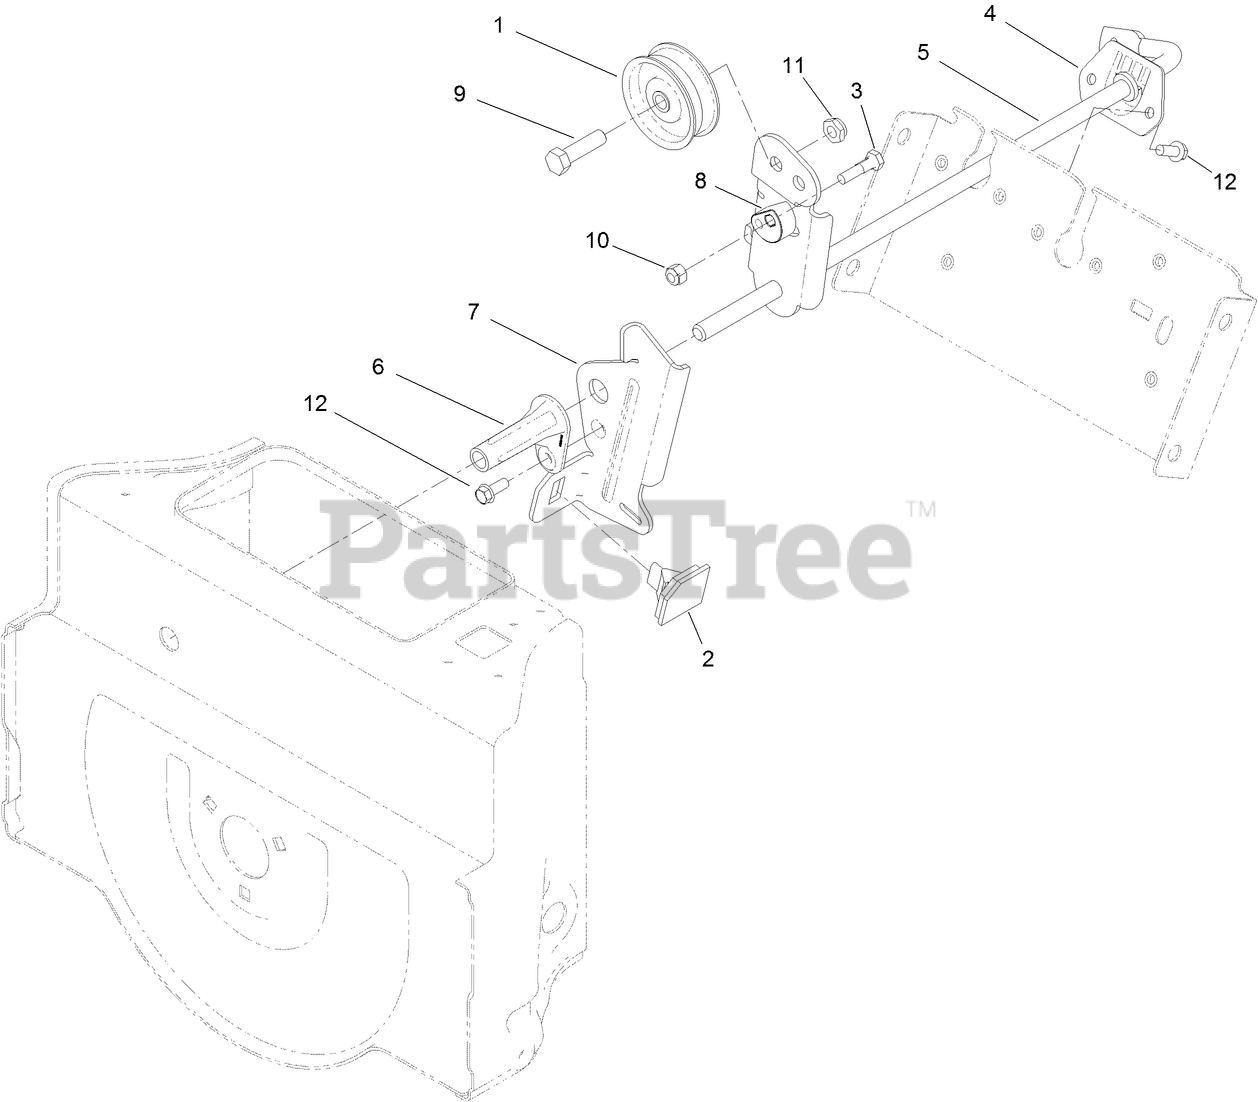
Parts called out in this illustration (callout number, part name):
1	PULLEY-IDLER
2	PAD-BRAKE
3	BOLT-PIVOT, ECCENTRIC
4	BUSHING-ROD, CLUTCH
5	IMPELLER CLUTCH ASM
6	PIVOT-BRAKE, IMPELLER
7	ARM-BRAKE, IMPELLER
8	ECCENTRIC-BRAKE, IMPELLER
9	SCREW-HH
10	NUT-LOCK, NI
12	SCREW-HWH
